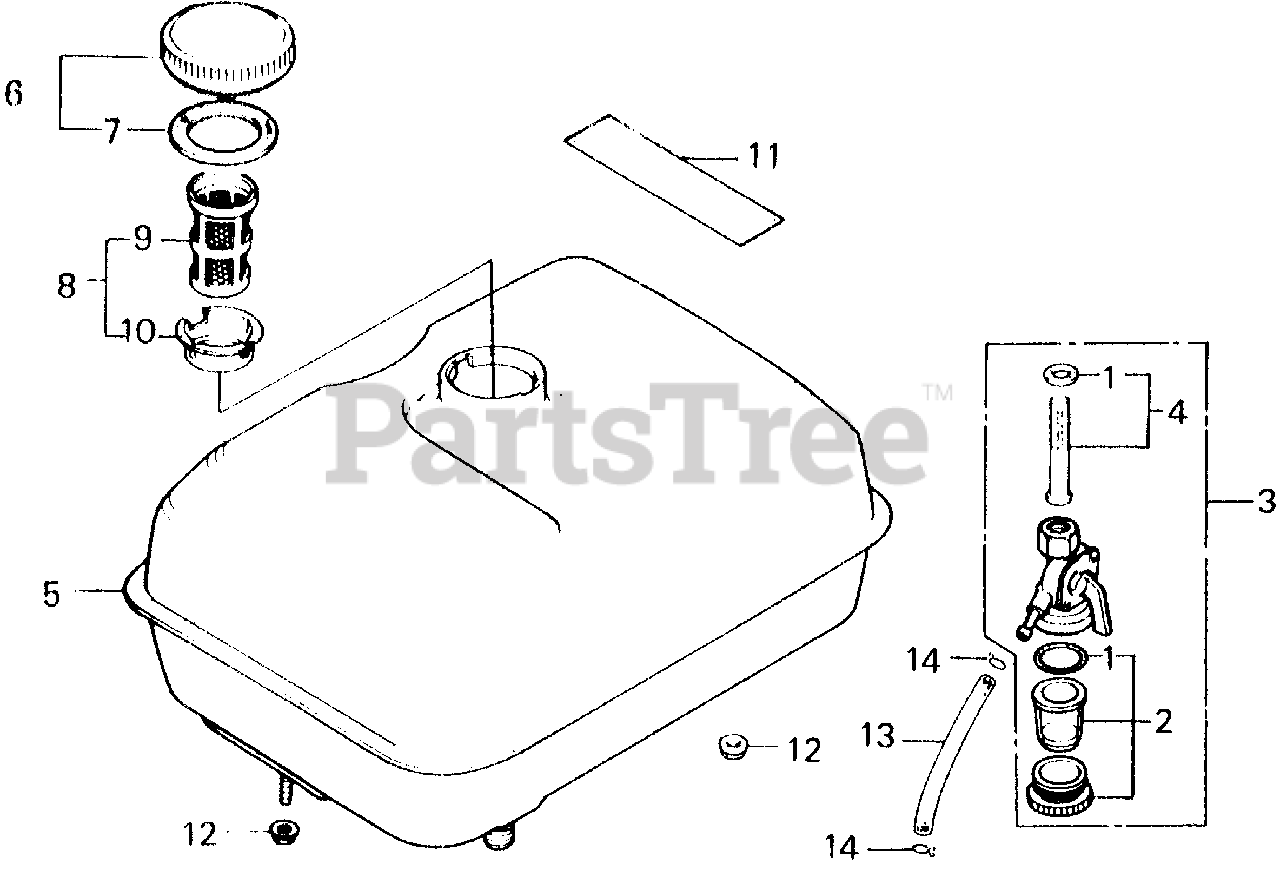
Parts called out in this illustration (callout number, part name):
1	GASKET SET, VALVE
2	CUP SET, FUEL STRAINER
3	PETCOCK ASSY.
4	SCREEN SET
5	TANK, FUEL *NH31* (MCKINLEY WHITE)
6	CAP, FUEL FILLER
7	GASKET, FUEL FILLER CAP
8	FILTER, FUEL
9	FILTER, FUEL
10	HOLDER, FUEL FILTER
11	MARK, CAUTION (ENGLISH/FRENCH)(SPANISH)
12	NUT, FLANGE (6MM)
13	BULK HOSE, FUEL (4.5X3000) (4.5X70)
14	CLIP, TUBE (B8)
